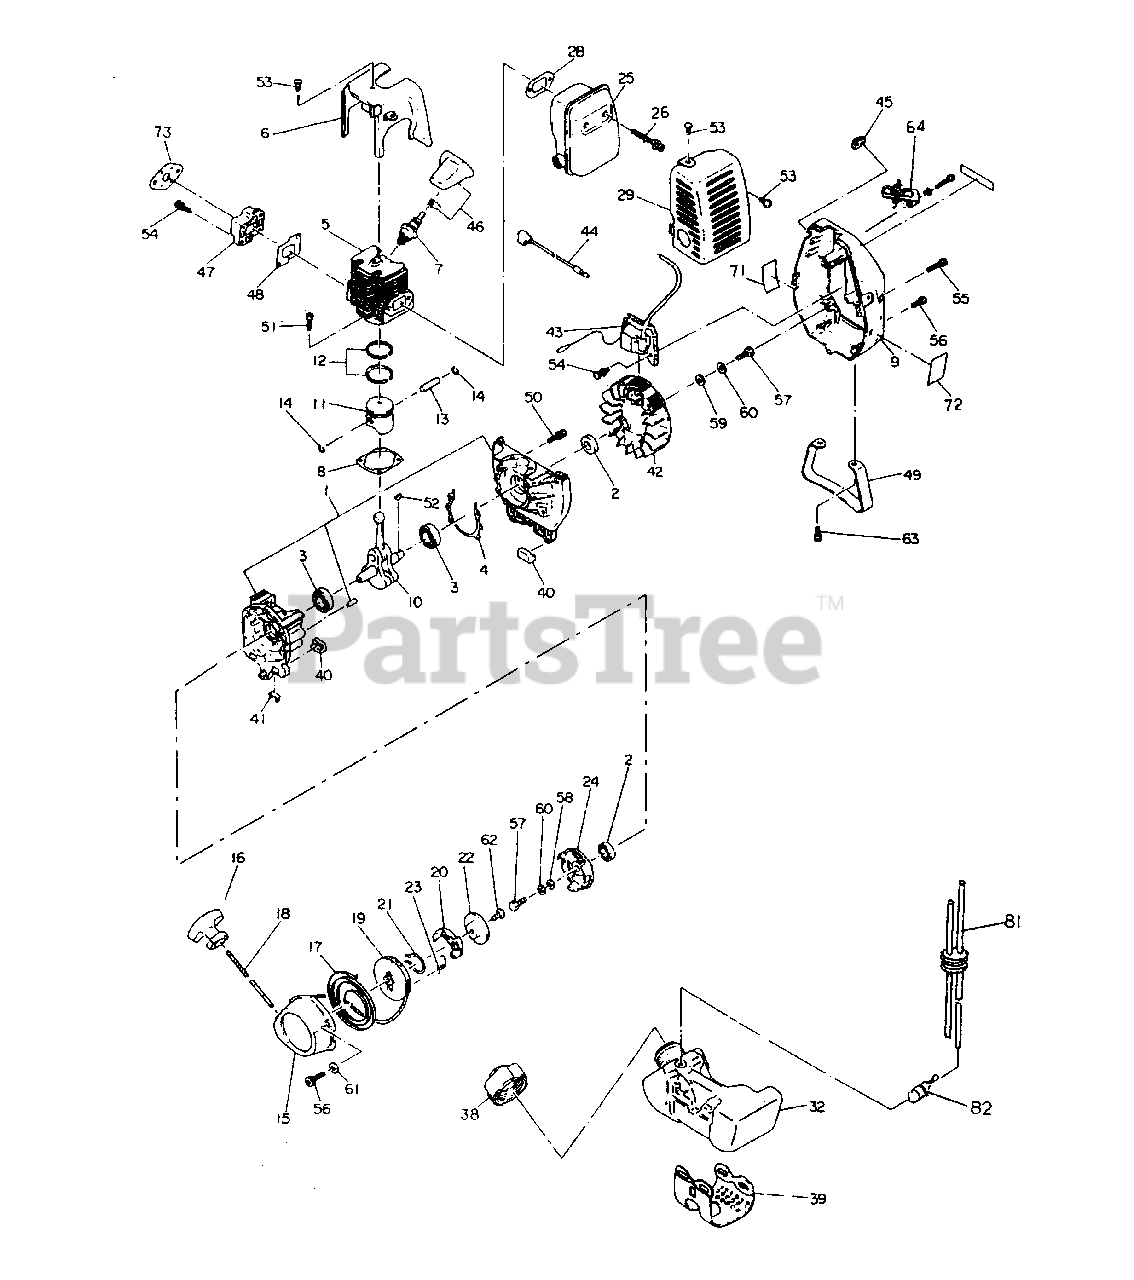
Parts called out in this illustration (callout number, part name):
1	Crankcase (Incl. 2-4)
2	Oil Seal
3	Ball Bearing
4	Gasket, Crankcase
5	Cylinder
6	Cylinder Cover
7	Spark Plug-NGK BM7A
8	Gasket, Cylinder
9	Fan Cover
10	Crankshaft Assembly
12	Piston Ring
15	Recoil Ass'y Kit (Incl 16-23)
16	Starter Knob
17	Spiral Spring
18	Starter Rope
20	Ratchet
21	Friction Spring
22	Friction Plate
23	Return Spring
25	Muffler, Complete
26	Bolt, Muffler
28	Gasket, Muffler
29	Muffler Cover
32	Fuel Tank
38	Fuel Tank Cap
39	Tank Bank
40	Rubber Cushion
41	Spacer, Tank Band
42	Flywheel
43	Igniter
44	Ignition Wire
45	Grommet
46	Spark Plug Cap
47	Insulator
48	Gasket, Insulator
50	Screw & Washer Ass'y
51	Bolt, Socket Head
52	Woodruff Key
54	Screw & Washer Ass'y
55	Bolt, Socket Head
56	Bolt, Socket Head
60	Spring Washer
63	Bolt, Socket Head
73	Gasket, Air Cleaner
